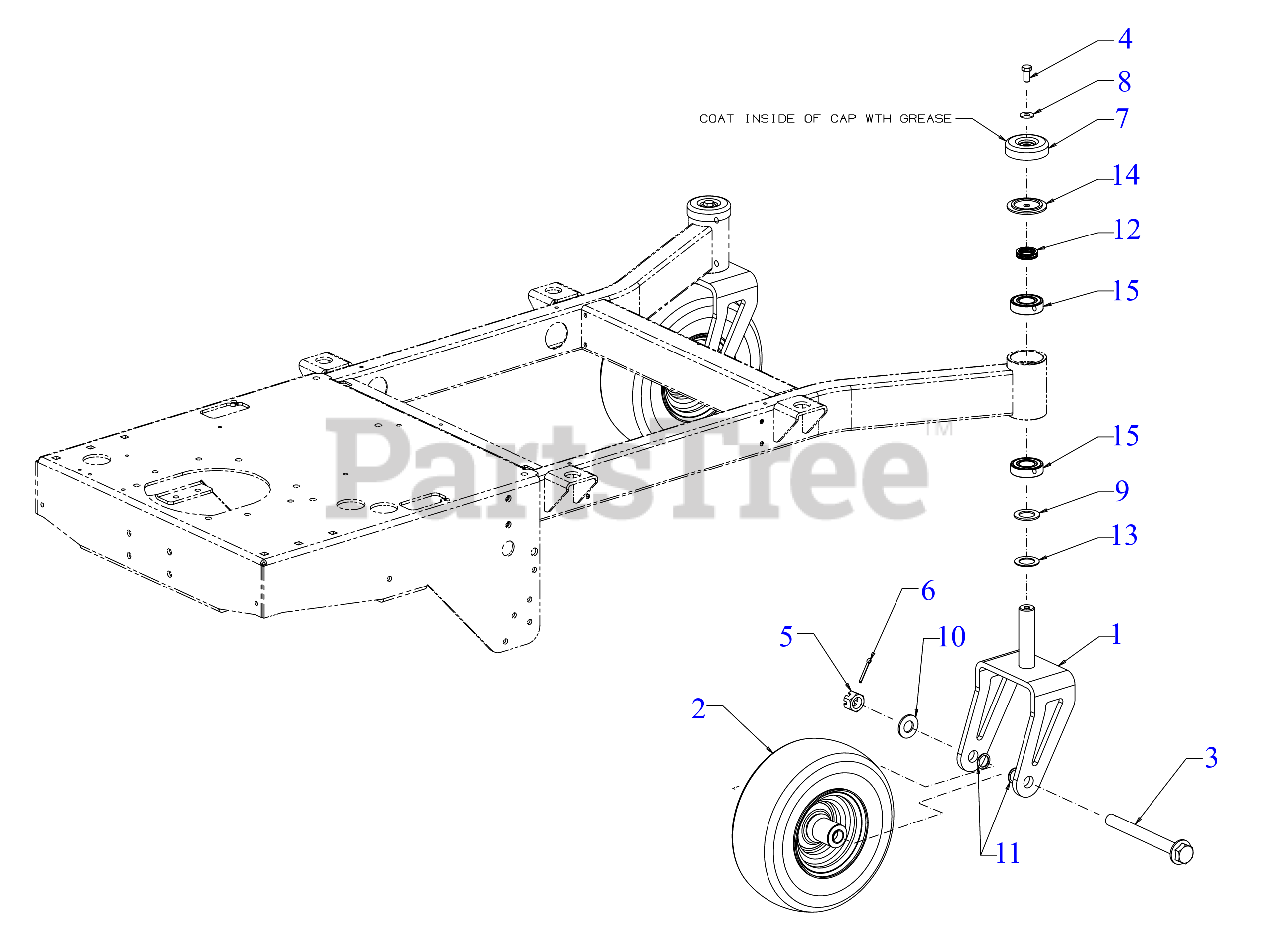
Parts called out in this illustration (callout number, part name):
2	WHEEL ASSEMBLY (11 x 4 - 5 SIMI PNE)
3	HEX FLANGE BOLT 3/4-16x7.0 GR5
4	SCREW 3/8-16 x .75 GR 5
5	HEX NUT CASTLE 3/4-16
6	COTTER PIN-5/32 DIA
7	AXLE CAP 2.5"
8	FLAT WASHER .385X.870X.090
9	FLAT WASHER 1.031 X1.62 X.095
10	FLAT WASHER
11	FLAT WASHER .750X1.000X.060:HD
12	WAVE WASHER
13	WASHER 1.010X1.560X.060
14	SHOULDER SPACER
15	BALL BEARING (1.0 x 52 x 15)
